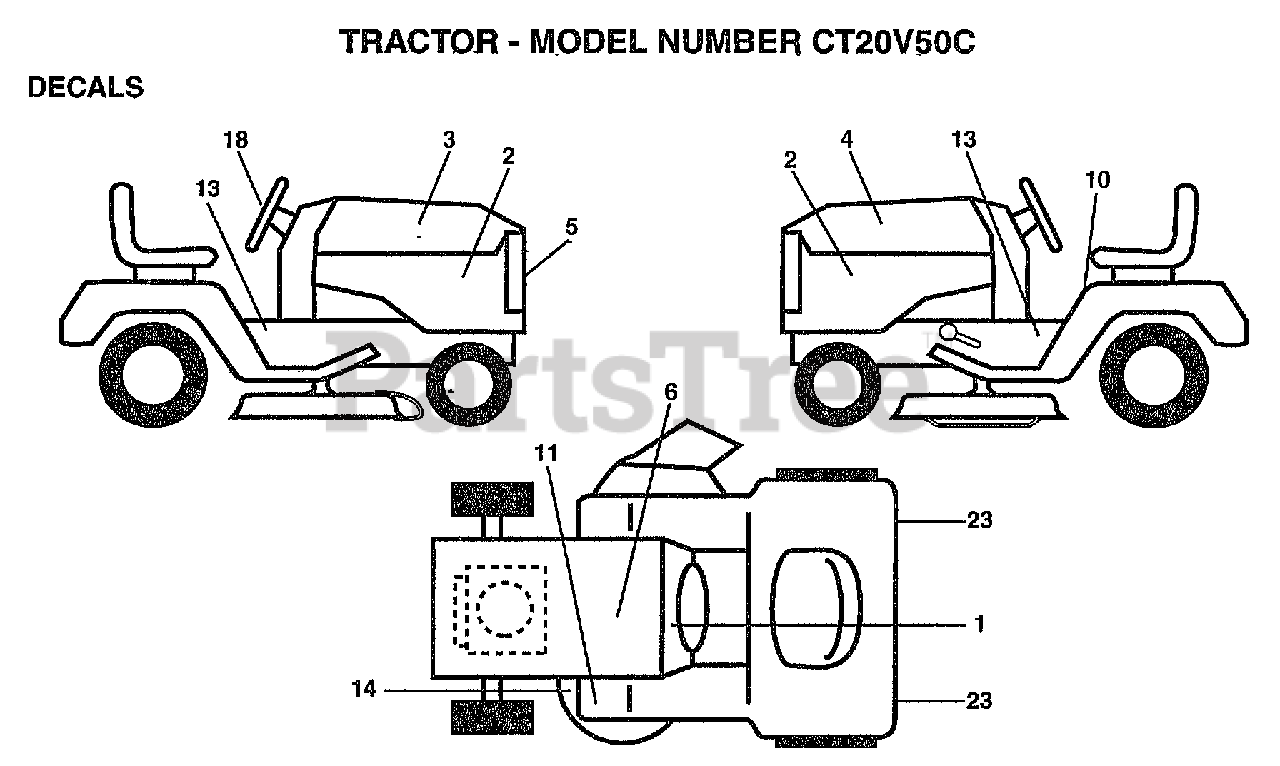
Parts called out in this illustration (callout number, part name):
1	"DECAL-OPER,GEAR D"
2	"DECAL PANEL,SIDE"
3	"DECAL HOOD,RH 20H"
4	"DECAL HOOD,LH 20H"
5	DECAL GRILLE
6	HARNESS.IGN.KOHLE
10	"DECAL DANGER,FEND"
13	"DECAL CHASSIS,50"""
14	"DECAL.V.BELT.44"""
18	DECAL INST STG WH
23	REFLECTOR-TAIL YT
